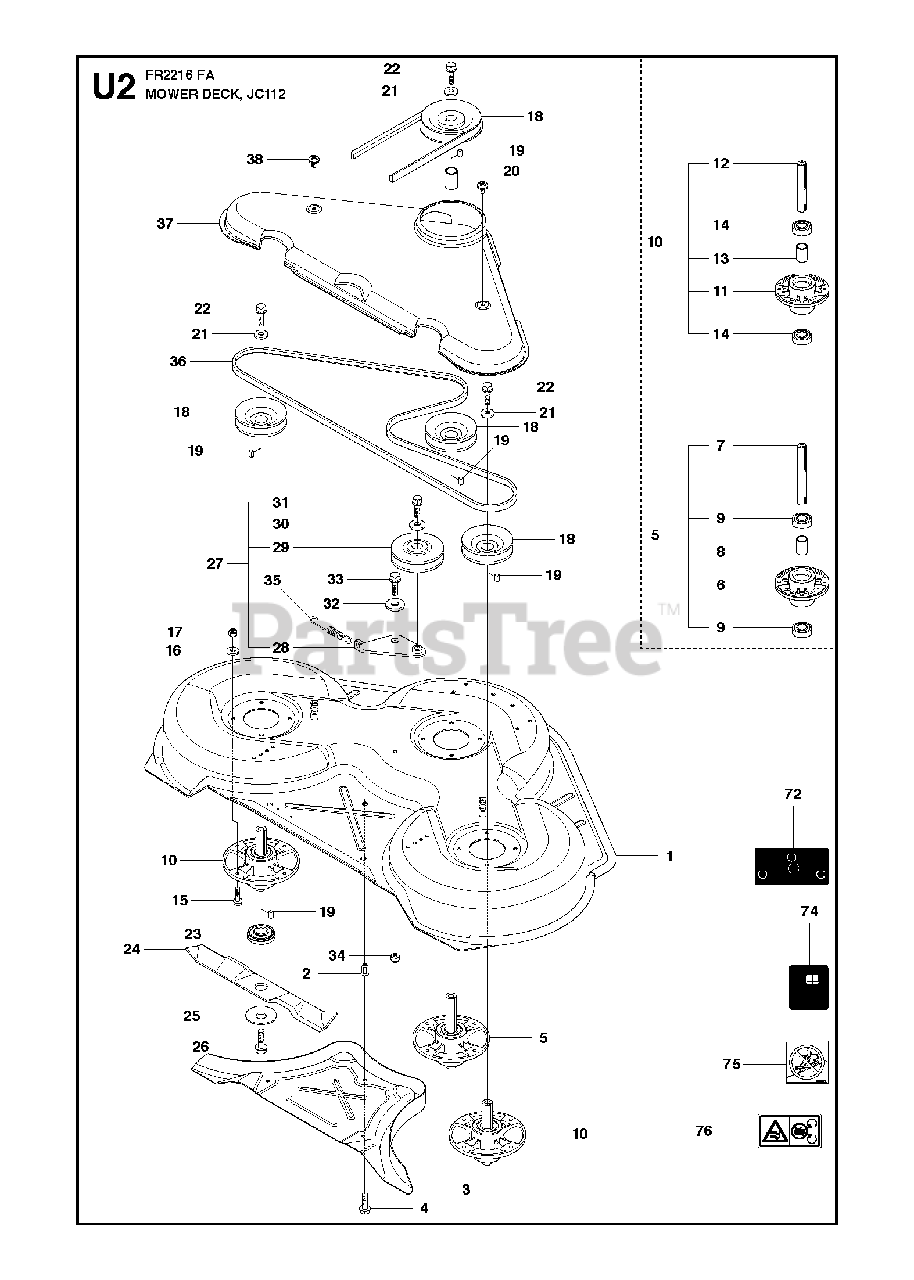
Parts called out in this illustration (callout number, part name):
5	BLADE HOUSING ASSY
6	BEARING HOUSING
7	SHAFT
8	SPACING SLEEVE
9	BEARING
10	BLADE HOUSING ASSY
11	BEARING HOUSING
12	SHAFT
13	SPACING SLEEVE
14	BEARING
16	WASHER BRB 8.4X17
17	LOCKNUT M8
24	BLADE
27	BELT TENSIONER ASSY
28	BELT TENSIONING ARM
29	PULLEY
30	SPACER
31	BOLT
32	WASHER
34	LOCKNUT M8
36	BELT
